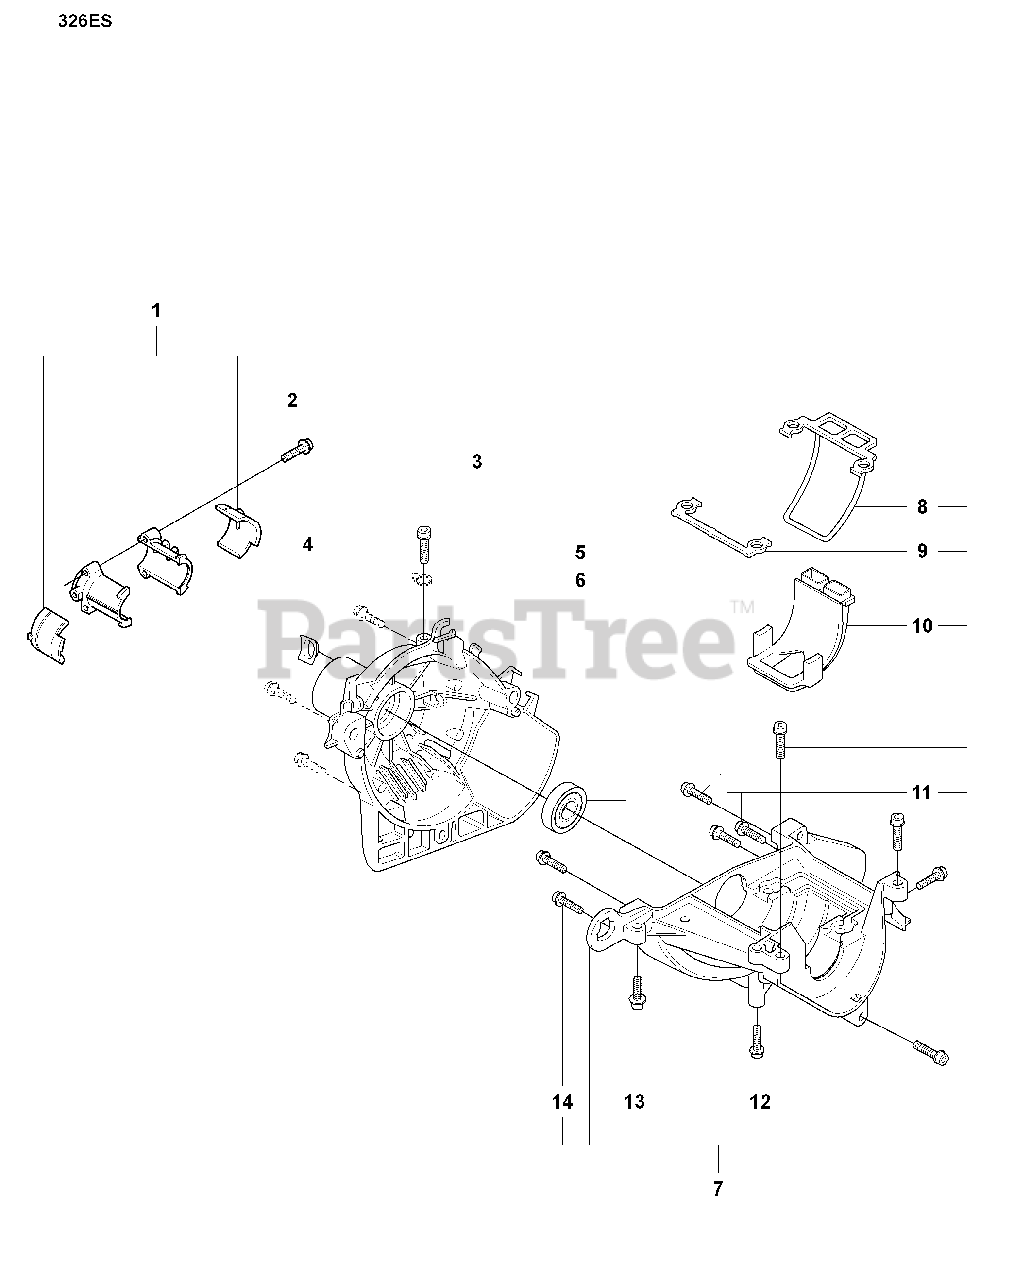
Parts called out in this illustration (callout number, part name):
1	COMPRESION SLEEVE/ISOLATOR SET
3	RP CLUTCH COVER
4	PROTECTION PLATE
7	CRANKCASE
